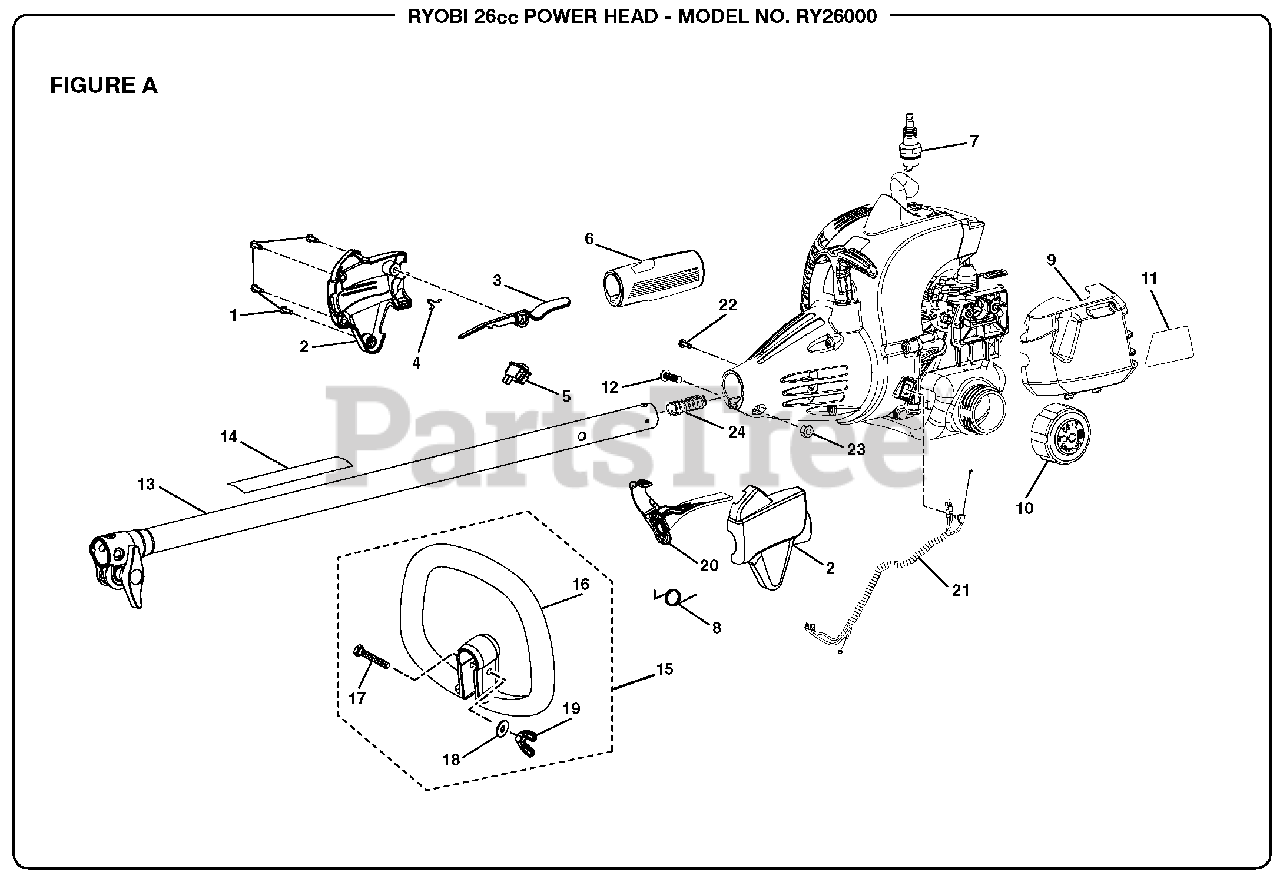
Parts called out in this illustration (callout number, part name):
1	Screw (M4 x 20 mm)
2	Control Handle Assembly
3	Trigger Lock
4	Strap Hanger
5	Switch (Momentary Contact)
6	Rear Handle
7	Spark Plug (Champion RCJ6Y)
9	Air Box Cover
10	Fuel Cap Assembly (1.5 in. Diameter)
11	Label
12	Bolt (M6 x 20 mm)
13	Upper Boom Assembly
14	Warning Decal
15	Front Handle Assembly
16	Front Handle
17	Bolt (1/4-20 x 40 mm)
19	Wing Nut (1/4-20)
20	Throttle Trigger
21	Throttle and Lead Assembly (Incl. Key No. 5)
22	Screw (8-16 x 5/16 in. Torx T.F.)
23	Hex Nut (M6)
24	Compression Spring
